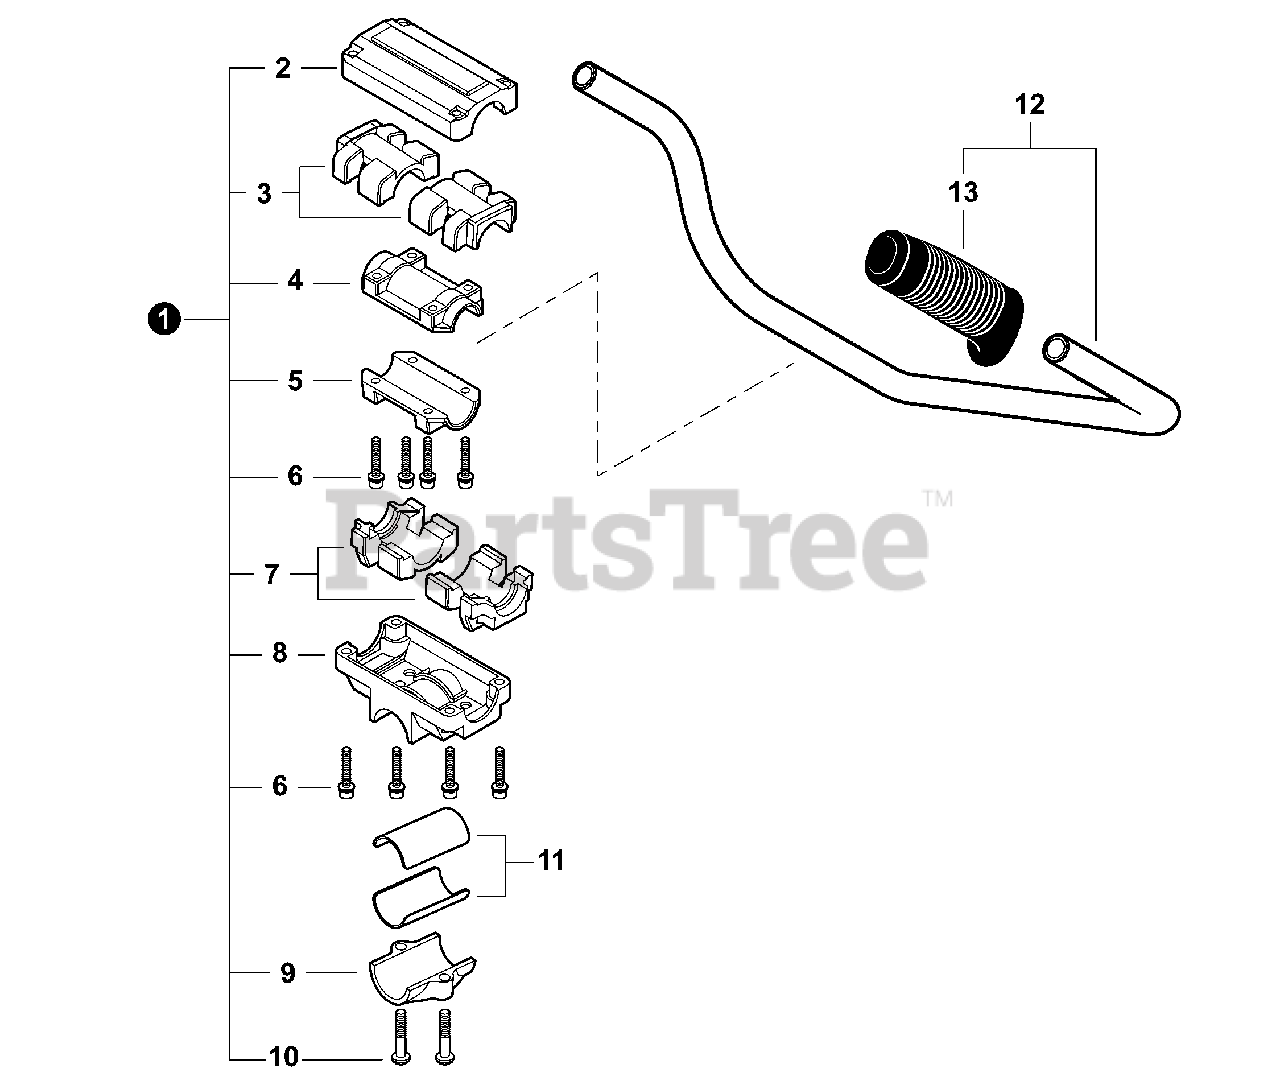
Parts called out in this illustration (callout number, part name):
1	BRACKET ASSY, HANDLEBAR
2	BRACKET, UPPER
3	CUSHION, UPPER
4	CLAMP, UPPER
5	CLAMP, LOWER
6	BOLT M5×25
7	CUSHION, LOWER
8	BRACKET, LOWER
9	BRACKET, MOUNTING
10	SCREW M6×25
12	HANDLEBAR ASSY
